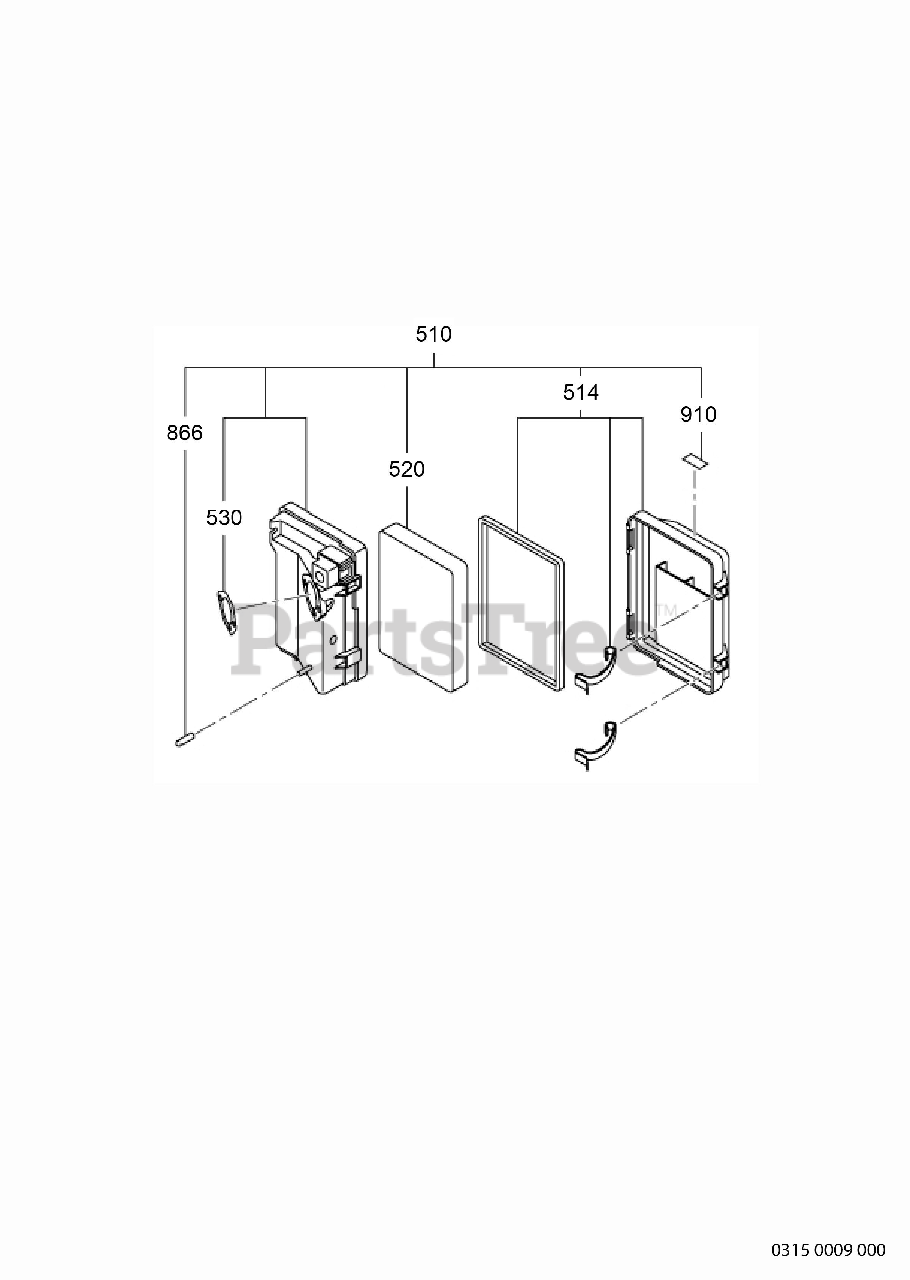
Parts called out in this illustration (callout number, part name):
510	AIR CLEANER AY
514	CLEANER COVER CP
520	ELEMENT
530	GASKET
866	CAP
